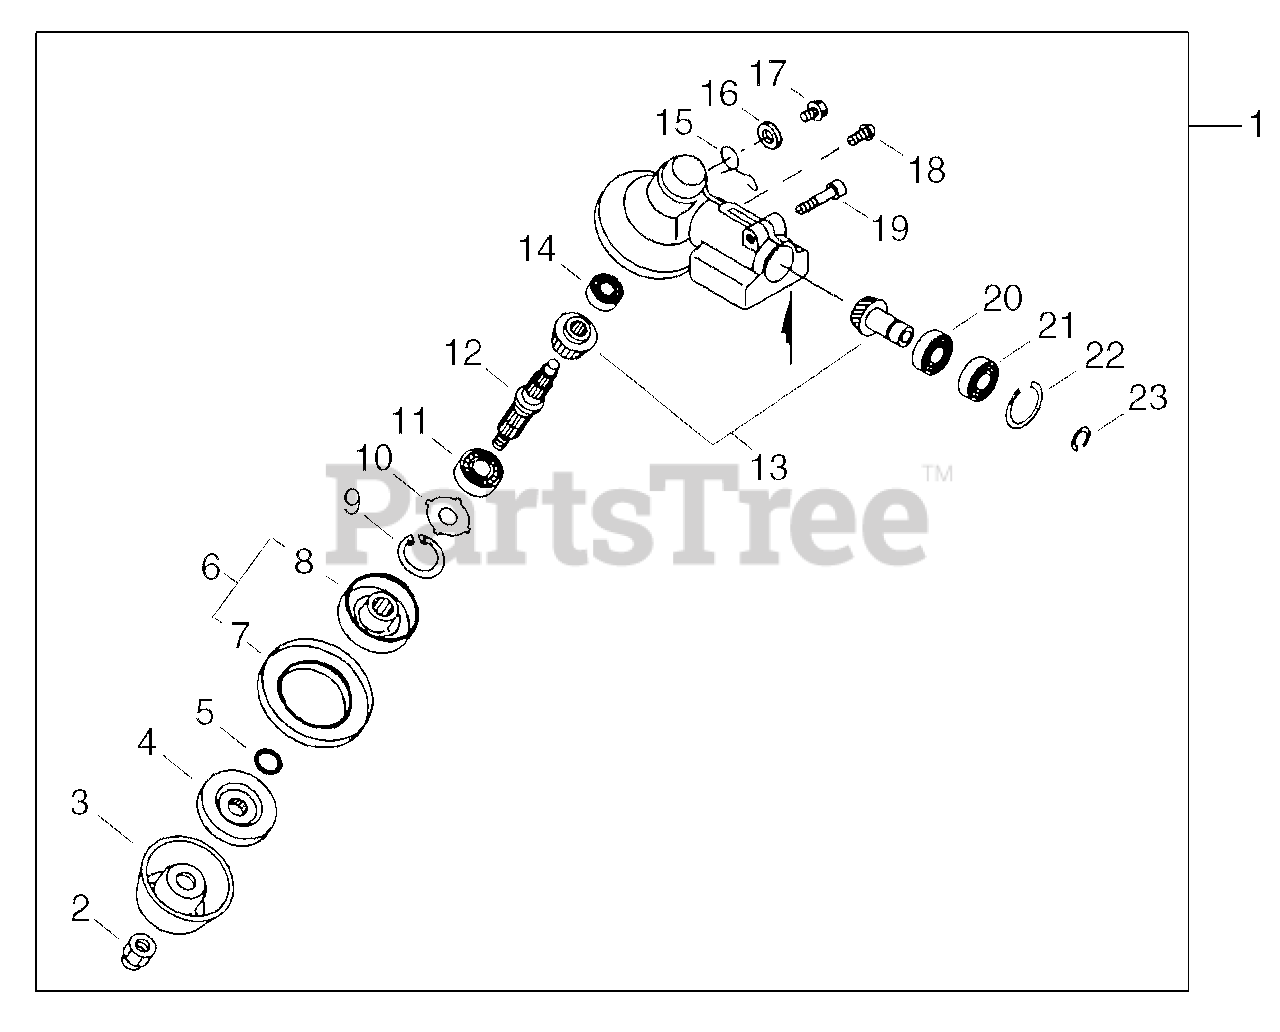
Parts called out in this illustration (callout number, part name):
1	CASE, GEAR
2	NUT, LOCK 10 - NYLON INSERT
4	PLATE, ADAPTOR - LOWER
5	O-RING 12 MM
6	RETAINER ASSY, BLADE
7	PLATE, ADAPTOR - LOWER
8	RETAINER, BLADE
9	RING, SNAP Ø32
11	BEARING, BALL 6201
12	SHAFT, GEAR
13	GEAR SET
14	BEARING, BALL 629
15	SPRING, TORSION
16	WASHER 8.5×18×0.8T
17	BOLT M8×8
18	SCREW 5×10
19	BOLT 6×30
20	BEARING, BALL 6001
21	BEARING, BALL 6001Z
22	RING, SNAP 28
23	RING, RETAINING - 12
